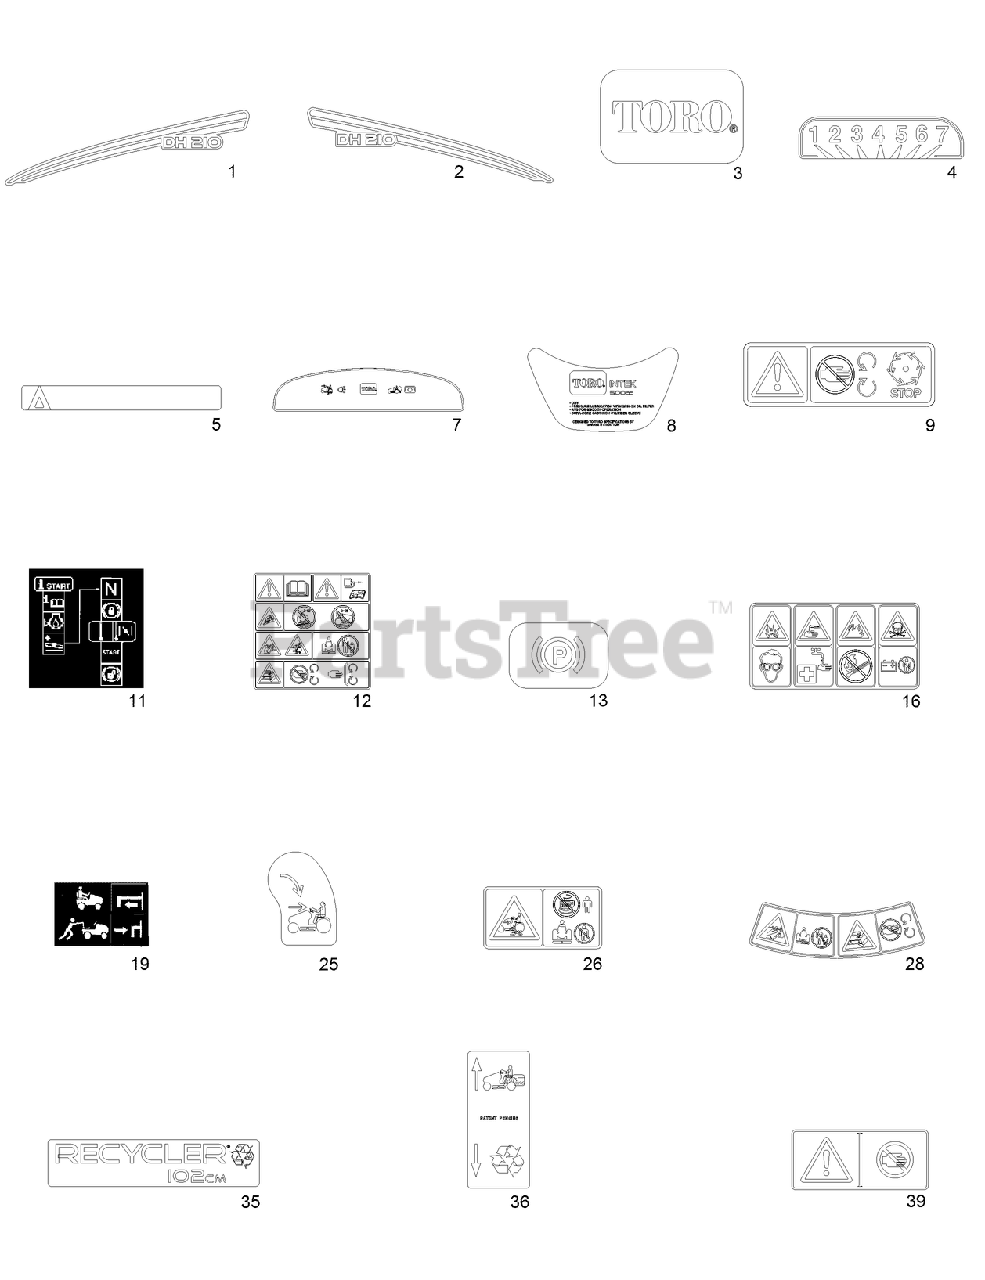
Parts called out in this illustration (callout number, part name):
1	DECAL-HOOD, LEFT
2	DECAL-HOOD, RIGHT
4	DECAL-HOC
5	DECAL-HOC
7	DECAL-DASH, DH210
8	DECAL-ENGINE
9	DECAL-WARNING, HOOD
12	DECAL-DANGER
13	DECAL-BRAKE, PARKING
16	DECAL-DANGER
19	DECAL-BYPASS
25	DECAL-SWITCH
26	DECAL-DANGER
28	DECAL-DANGER
35	DECAL-RECYCLER
36	DECAL-OPERATION
39	DECAL-WARNING
